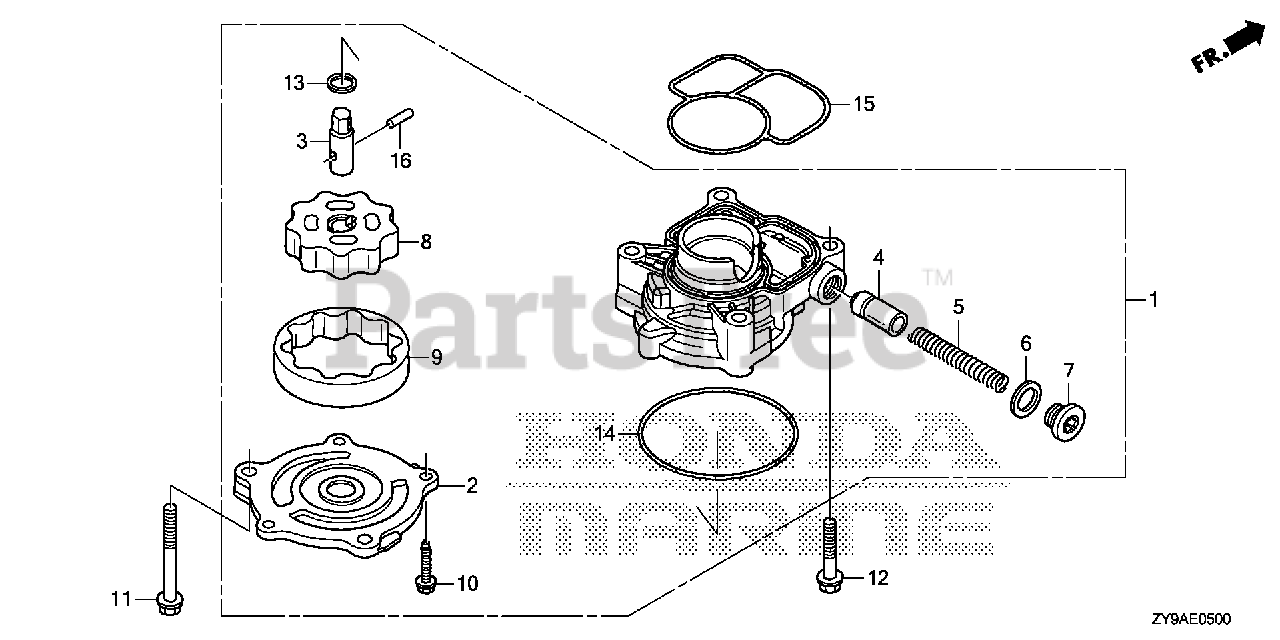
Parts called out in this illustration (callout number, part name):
1	PUMP ASSY., OIL
2	COVER, OIL PUMP
3	SHAFT, OIL PUMP
4	VALVE, RELIEF
5	SPRING, RELIEF VALVE
6	WASHER, SEALING (18MM)
7	BOLT, SEALING (18MM)
8	ROTOR (INNER)
9	ROTOR (OUTER)
10	BOLT, FLANGE (6X18) (CT200)
11	BOLT, FLANGE (8X60)
12	BOLT, FLANGE (8X40)
13	WASHER, THRUST (13MM)
14	O-RING, PUMP COVER
15	O-RING, OIL PUMP
16	ROLLER (5X17.8)
